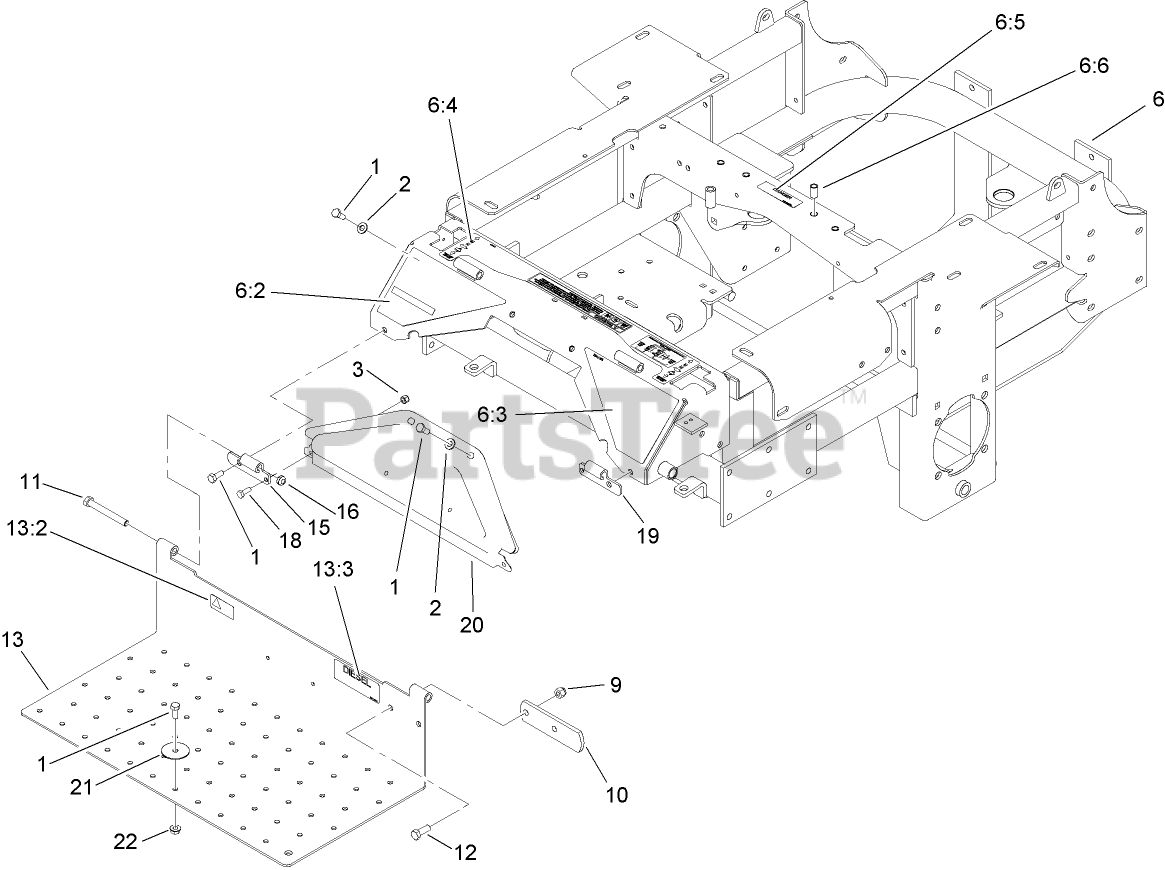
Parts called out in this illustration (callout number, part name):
1	SCREW-HH
2	WASHER-FLAT
3	NUT-LOCK, NI
6	MAIN FRAME ASM
6:2	DECAL-DANGER, LEFT
6:3	DECAL-WARNING, RIGHT
6:4	DECAL-CONSOLE, TOP (CE)
6:5	DECAL-WARNING
6:6	INSERT-THREADED
9	NUT-LOCK, NI
10	STOP-BRAKE, PARK
11	SCREW-HH
12	SCREW-HH
13	FLOOR PAN ASM
13:2	DECAL-PROTECTION, EAR
13:3	DECAL-DIESEL
15	Hinge-Floorpan, LH
16	NUT-LOCK, NI
18	SCREW-HH
19	Hinge-Floorpan, RH
20	Pocket
21	WASHER
22	NUT-HF
